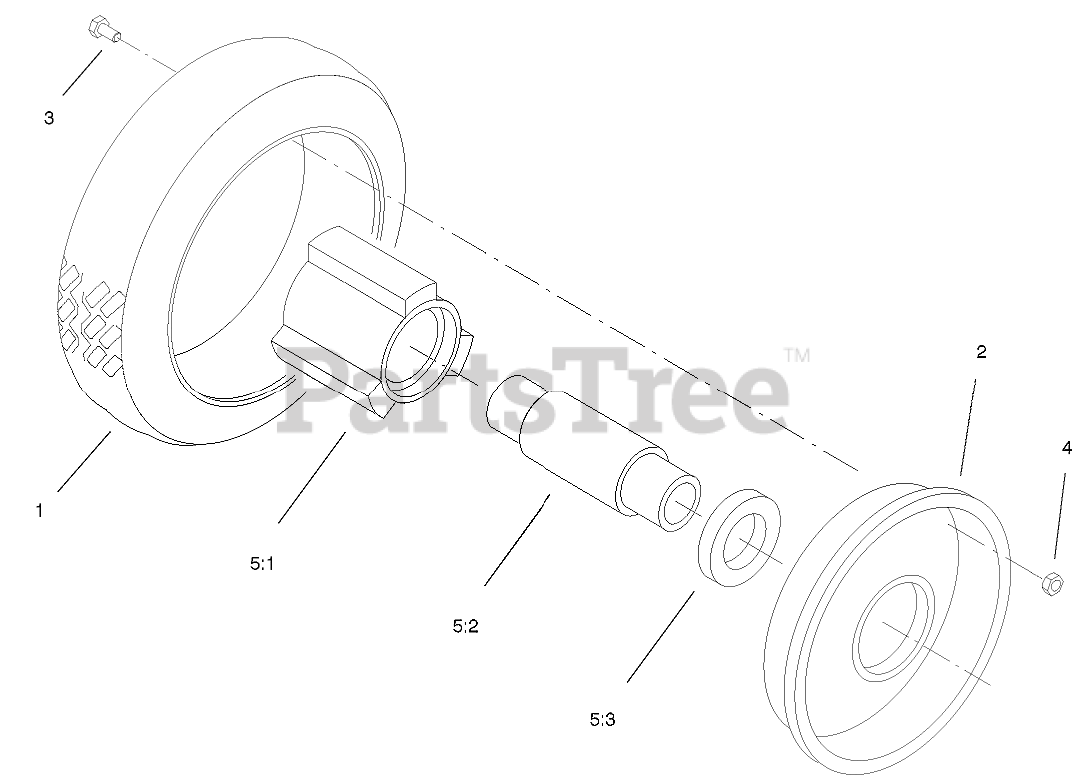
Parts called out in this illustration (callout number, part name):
2	PLATE-WHEEL, HALF
3	SCREW-HH
4	NUT-LOCK, NI
5	Hub and Bearing ASM
5:1	HUB-BEARING
5:2	SPACER-BEARING
5:3	BEARING-WHEEL
